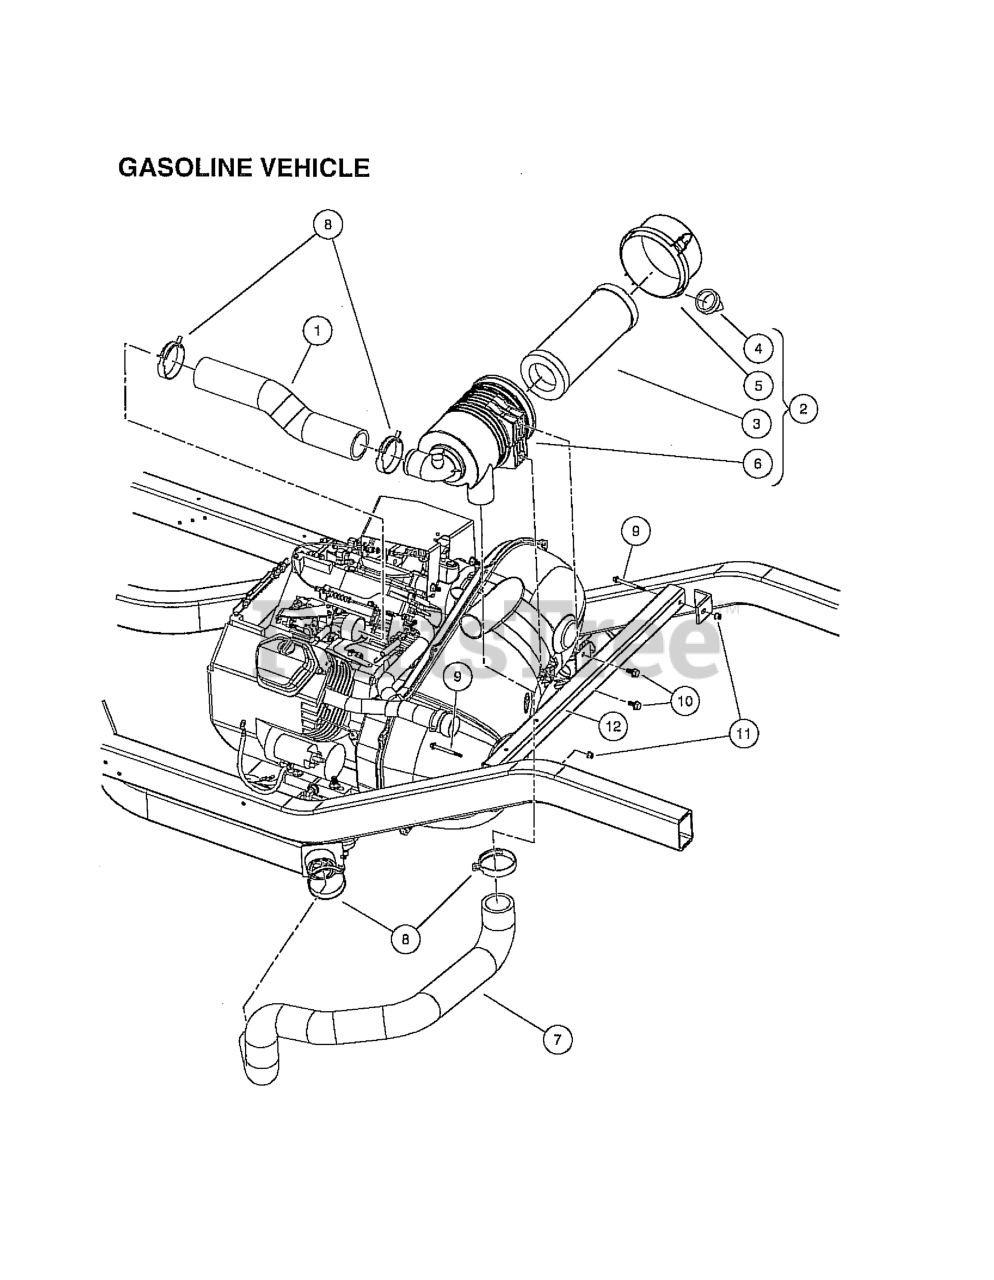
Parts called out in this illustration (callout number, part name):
1	HOSE, INTAKE, GX620
2	FILTER, AIR, CANISTER, 5IN
3	ELEMENT, FILTER, AIR, 5 IN
7	HOSE, INTAKE, PRIMARY
8	CLAMP, HOSE, CTB 64MM
9	BOLT-M6X1.0X65 HEX FL HD, BLK
10	BOLT FLG, M8X1.25X16 LOCTITE
11	NUT FLG, M6 X 1.0 NYLON
